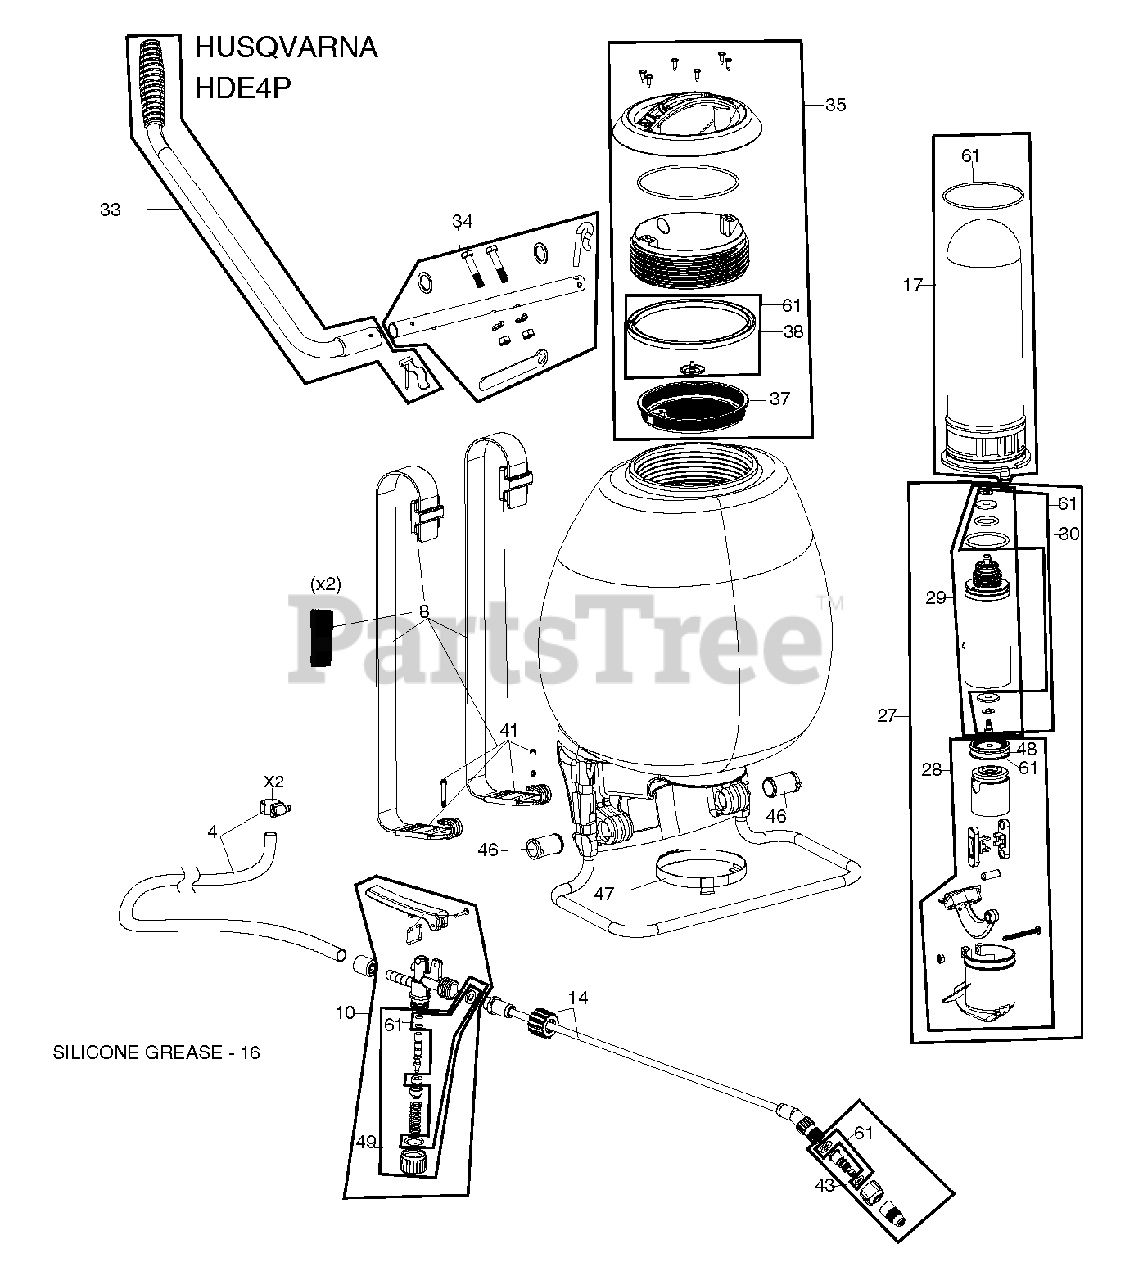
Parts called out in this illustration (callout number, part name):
4	HOSE AND 2 HOSE CLAMPS
8	SHOULDER STRAP ASSEMBLY
10	SPRAY GUN W/GRIP & PLASTIC HND
14	FIBERGLASS WAND 20
16	SILICONE GREASE
17	PRESSURE CHAMBER ORIN
27	G8 PISTON & CYLINDER COMPLETE
28	PISTON SEAL CONNECTIN
29	CYLINDER ASSY
30	DIAPHRAGM VITON SEALS
33	PUMP HANDLE BLACK
34	PUMP LEVER
35	BACKPACK LID SEAL
41	BUCKLE HOOK FOR STRAP
43	MET PUMP LVR W/LOCK RPINS WSHR
46	Nylon Bearing
47	RETENTION CLAMP
48	PISTON CUP G8
49	SPINDLE SET W VITON
61	SEAL SET COMPLETE HDE
